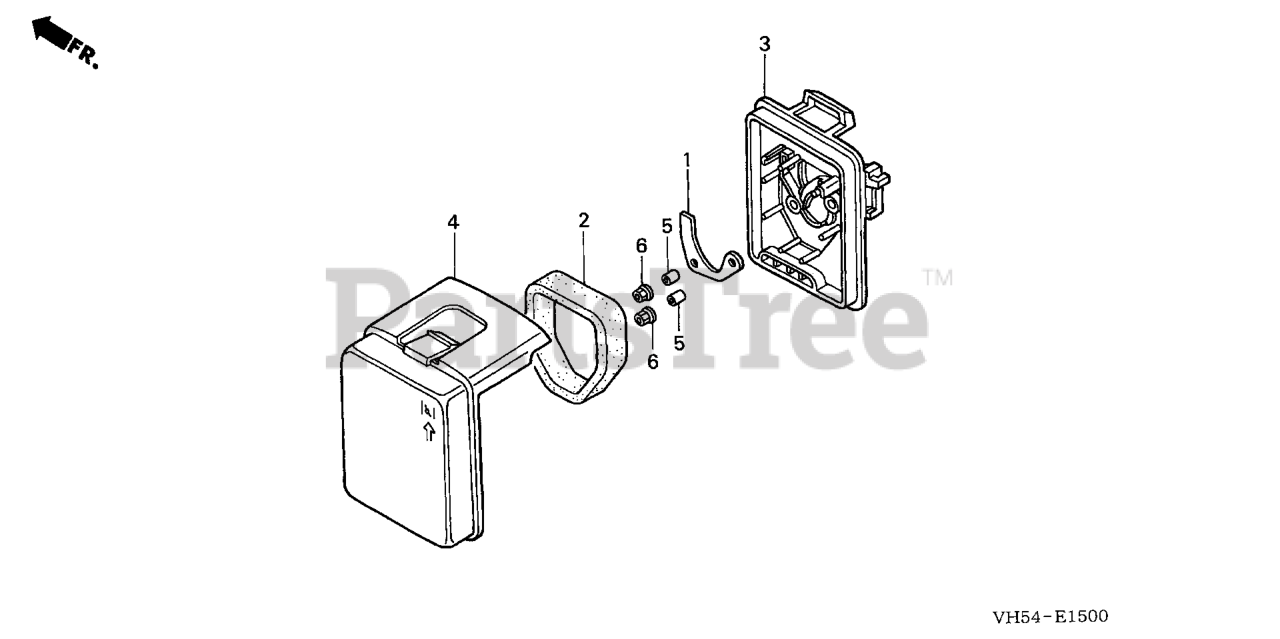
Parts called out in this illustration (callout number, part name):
1	PLATE, OIL TRAP
2	ELEMENT, AIR CLEANER
3	HOUSING, AIR CLEANER *NH1* (BLACK)
4	COVER, AIR CLEANER *NH1* (BLACK)
5	COLLAR, AIR CLEANER
6	NUT, FLANGE (5MM)
